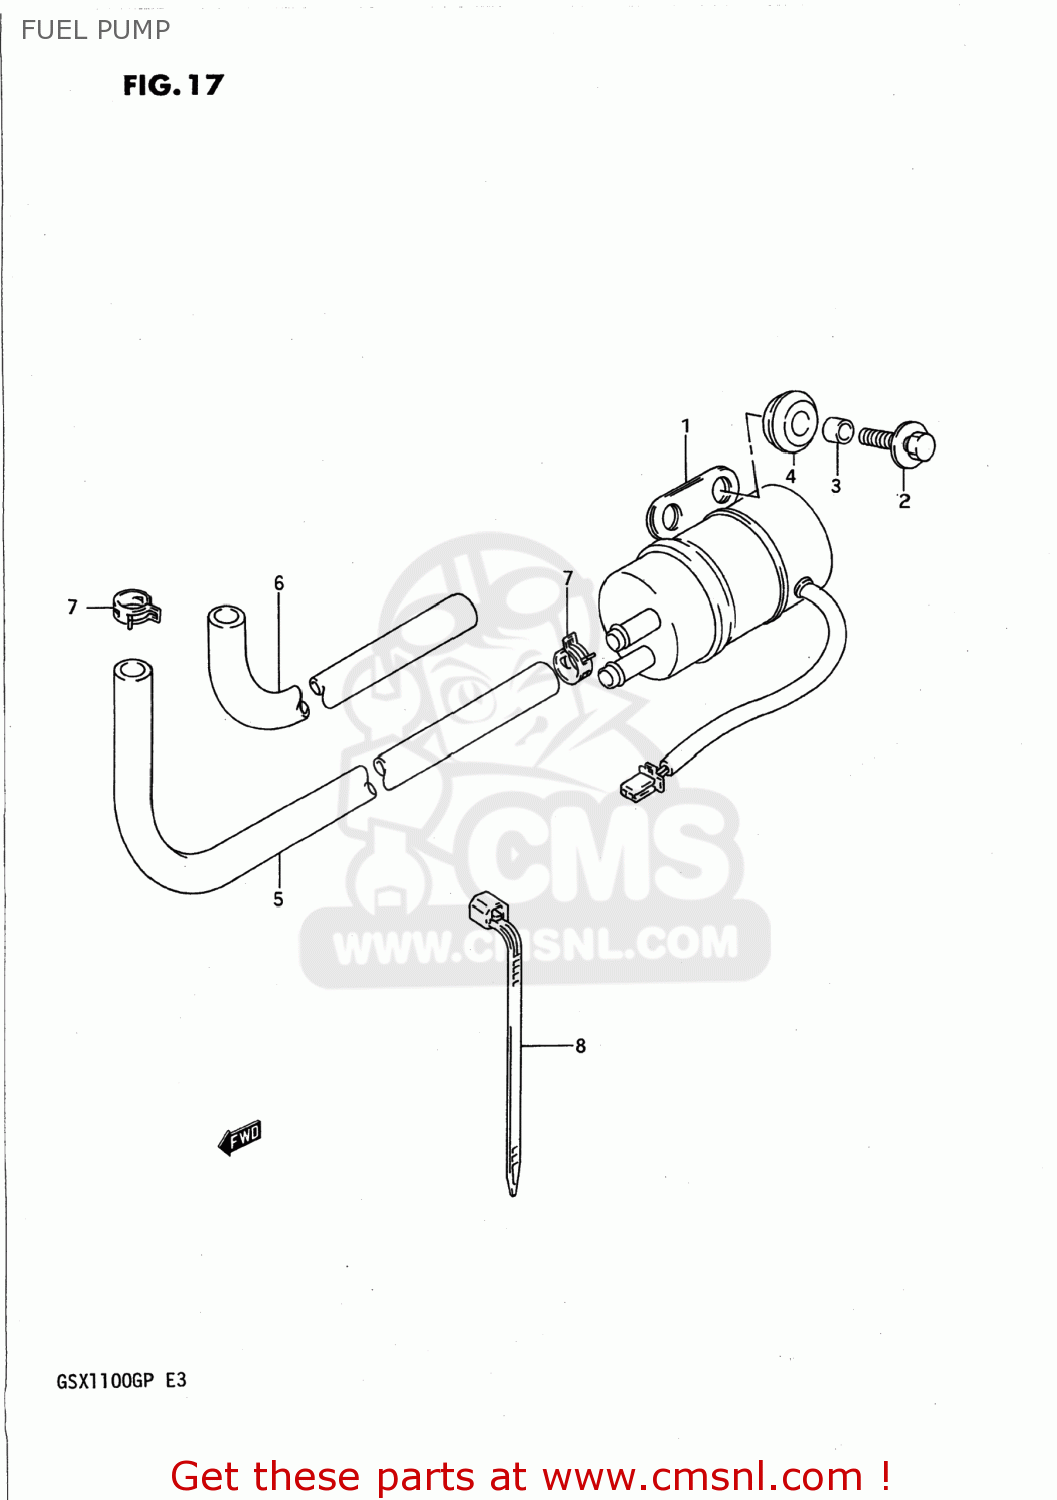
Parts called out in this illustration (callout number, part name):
1	PUMP ASSY,FUEL
2	BOLT(6X20)
3	SPACER (6.1X9X9)
4	CUSHION
5	HOSE (7X13X1000)
6	PROTECTOR(14.5X15.5X600)
7	CLIP
8	CLAMP(L:125)
